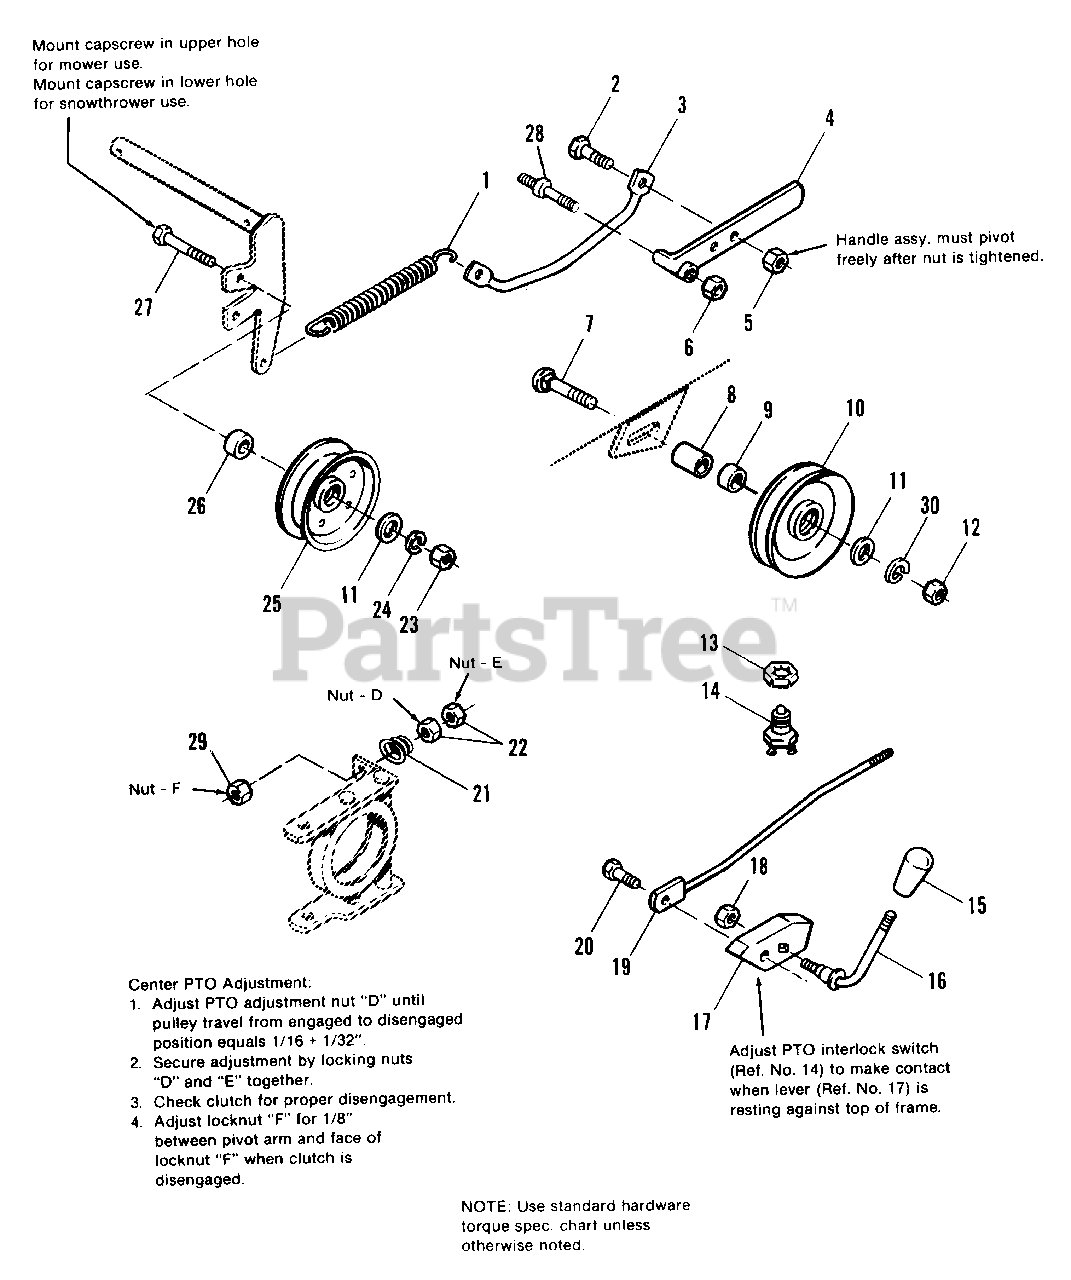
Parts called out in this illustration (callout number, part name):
1	SPRING, Tension
2	CAPSCREW, Hex Hd., 5/16-18 x 3/4
3	ROD, Tension
4	HANDLE ASSY.
5	LOCKNUT, Hex, 5/16-18
6	LOCKNUT, Hex, 7/16-14
7	BOLT, Carriage, 3/8-16 x 1-3/4
10	PULLEY ASSY., w/Bearings
11	WASHER, Plain, 3/8
12	LOCKNUT, Hex, Flange, 3/8-16
13	NUT, Pal
14	SWITCH, Interlock
15	KNOB
16	HANDLE, PTO, Clutch
18	LOCKNUT, Hex, 3/8-16
19	ROD ASSY., Control
20	CAPSCREW, Special
22	NUT, Hex, Full, 5/16-18
23	NUT, Hex, Full, 3/8-16;
24	LOCKWASHER, 3/8
25	PULLEY, Idler
29	LOCKNUT, Hex, Jam, Cntr., 5/16-18
30	LOCKWASHER, 3/8
